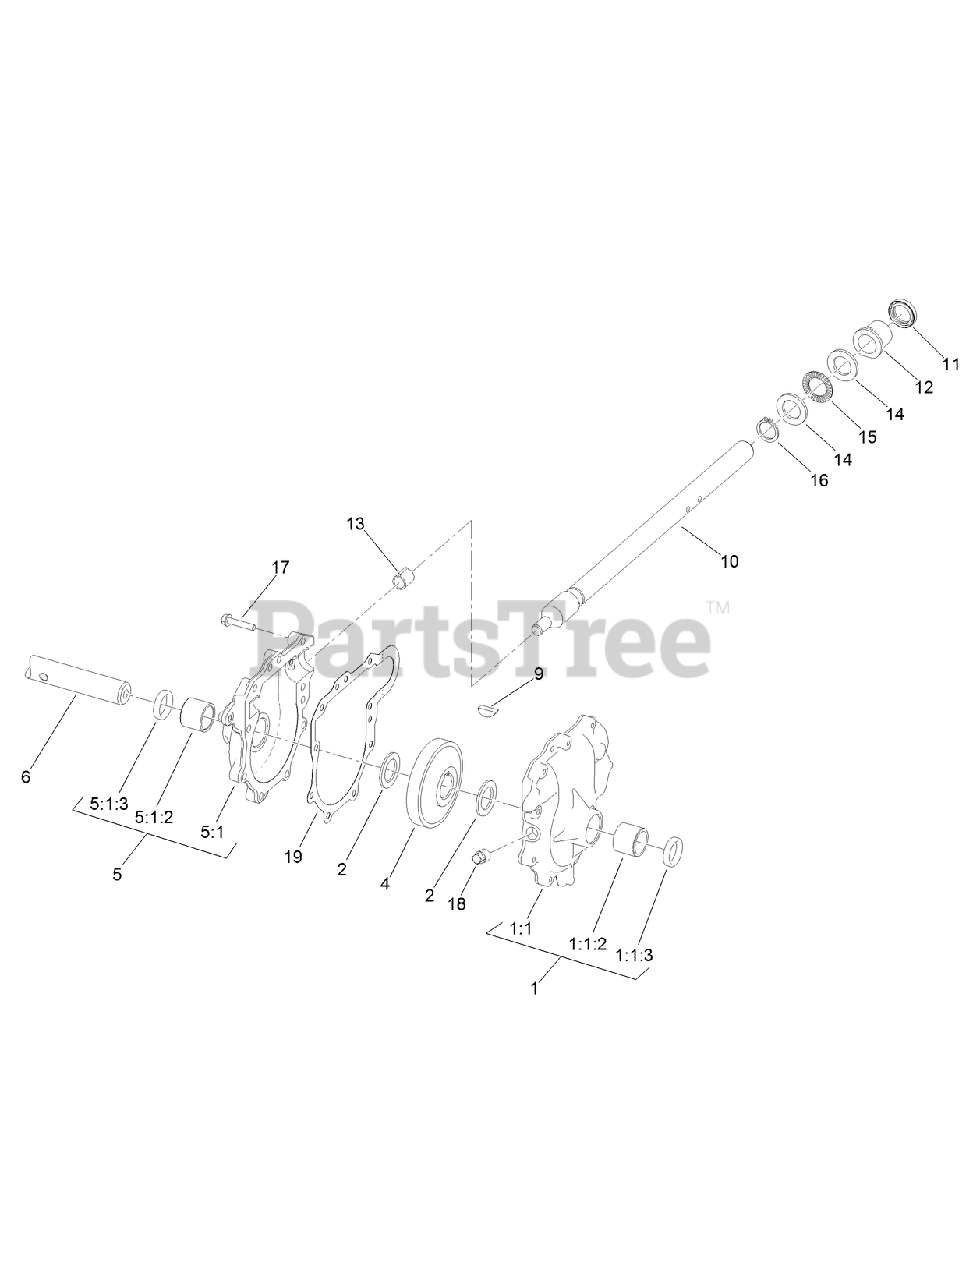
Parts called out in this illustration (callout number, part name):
1	LH AUGER GEARCASE ASM
1:1	Gearcase-Auger, LH
1:1:2	BUSHING-SLEEVE
1:1:3	SEAL-OIL
2	WASHER-THRUST
4	GEAR-HELICAL
5	RH AUGER GEARCASE ASM
5:1	GEARCASE-AUGER, RH
5:1:2	BUSHING-SLEEVE
5:1:3	SEAL-OIL
6	SHAFT-AUGER
9	KEY-WOODRUFF
10	SHAFT-IMPELLER
11	SEAL-OIL
12	BUSHING-INPUT
13	BUSHING-WORM
14	WASHER-THRUST
15	BEARING-THRUST
16	RING-RETAINING, Ext
17	SCREW-HWHTF
18	PLUG-PIPE, SQH
19	GASKET-GEARCASE, AUGER
